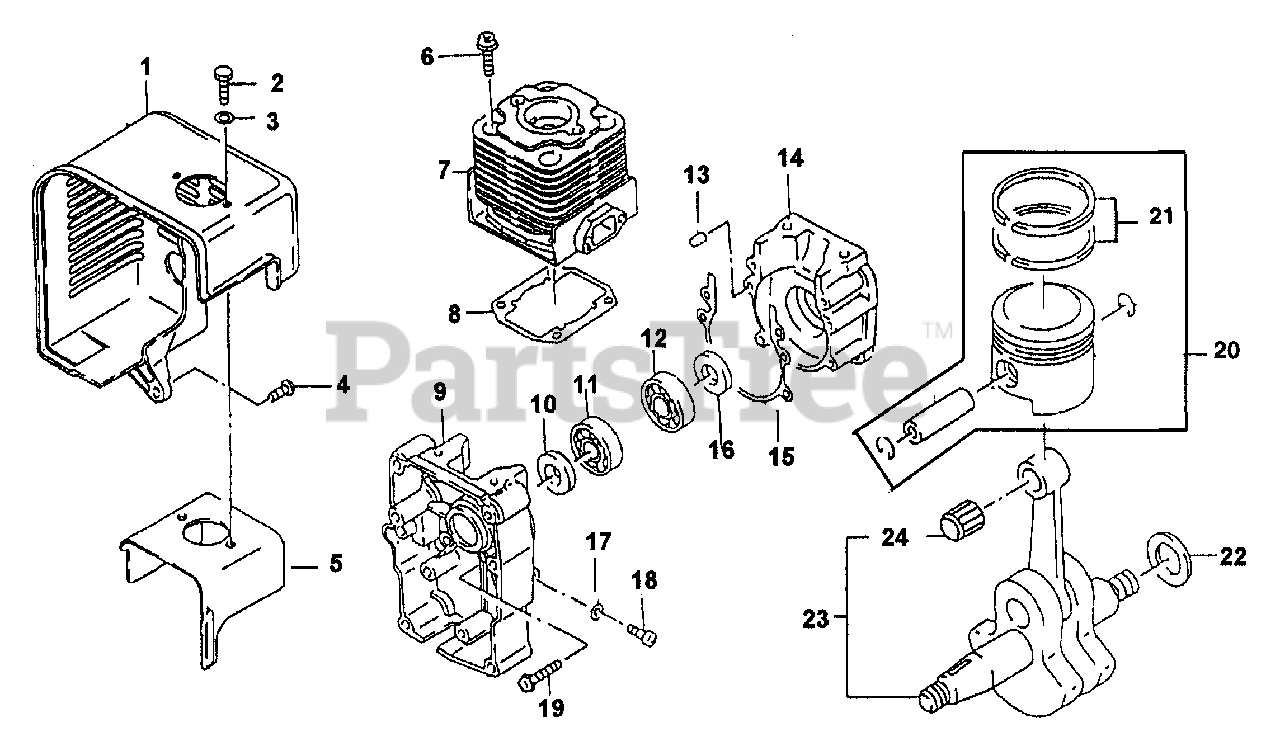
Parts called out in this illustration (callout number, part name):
1	SHROUD, ENGINE
2	BOLT
4	SCREW
5	SHROUD, ENGINE
6	BOLT
8	GASKET, CYLINDER
9	CRANKCASE
13	PIN DOWEL
14	CRANKCASE
15	GASKET, CRANKCASE
18	SCREW
19	SCREW
20	PISTON, ASSY.
21	RING SET, PISTON
22	SHIM T=0.10
23	CRANKSHAFT ASSY.
